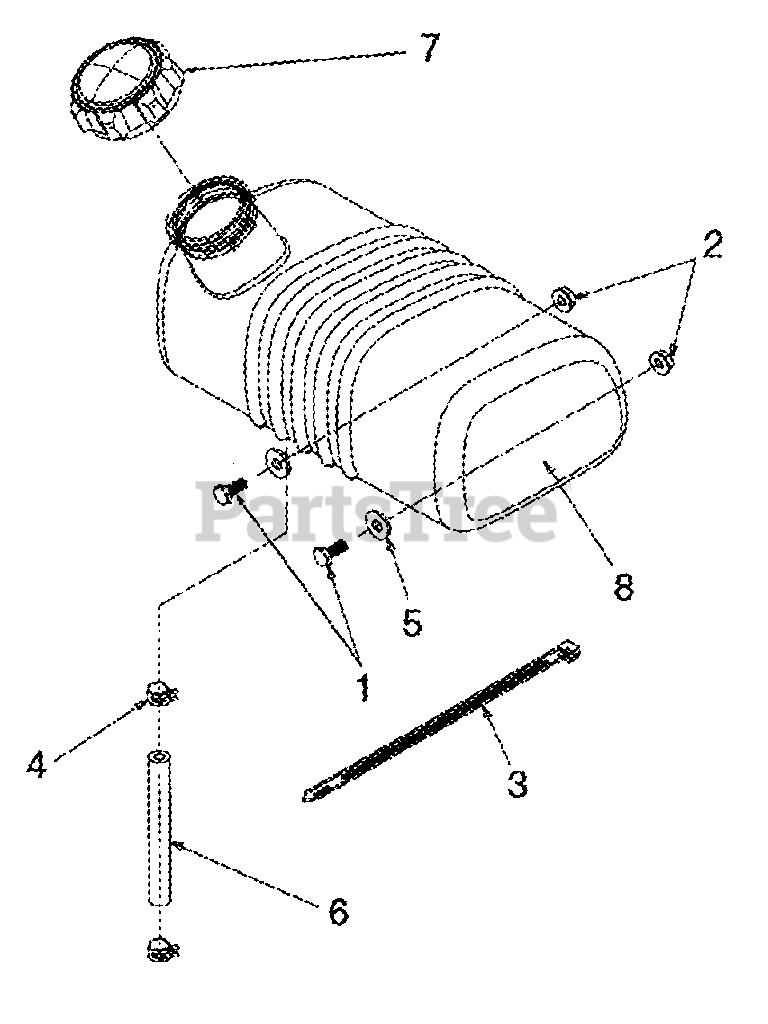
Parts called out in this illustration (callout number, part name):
1	Screw, Hex Cap, 1/4-20 x .62
2	Nut, Hex Flange Lock, 1/4-20
3	Cable Tie, 30.66 Lg
4	Clamp, Hose, 1/2 Inch
5	Washer, Flat, .28 x .74 x .063
6	Hose, Fuel Line 9 Inch
7	Cap, Fuel
8	Tank, Fuel
